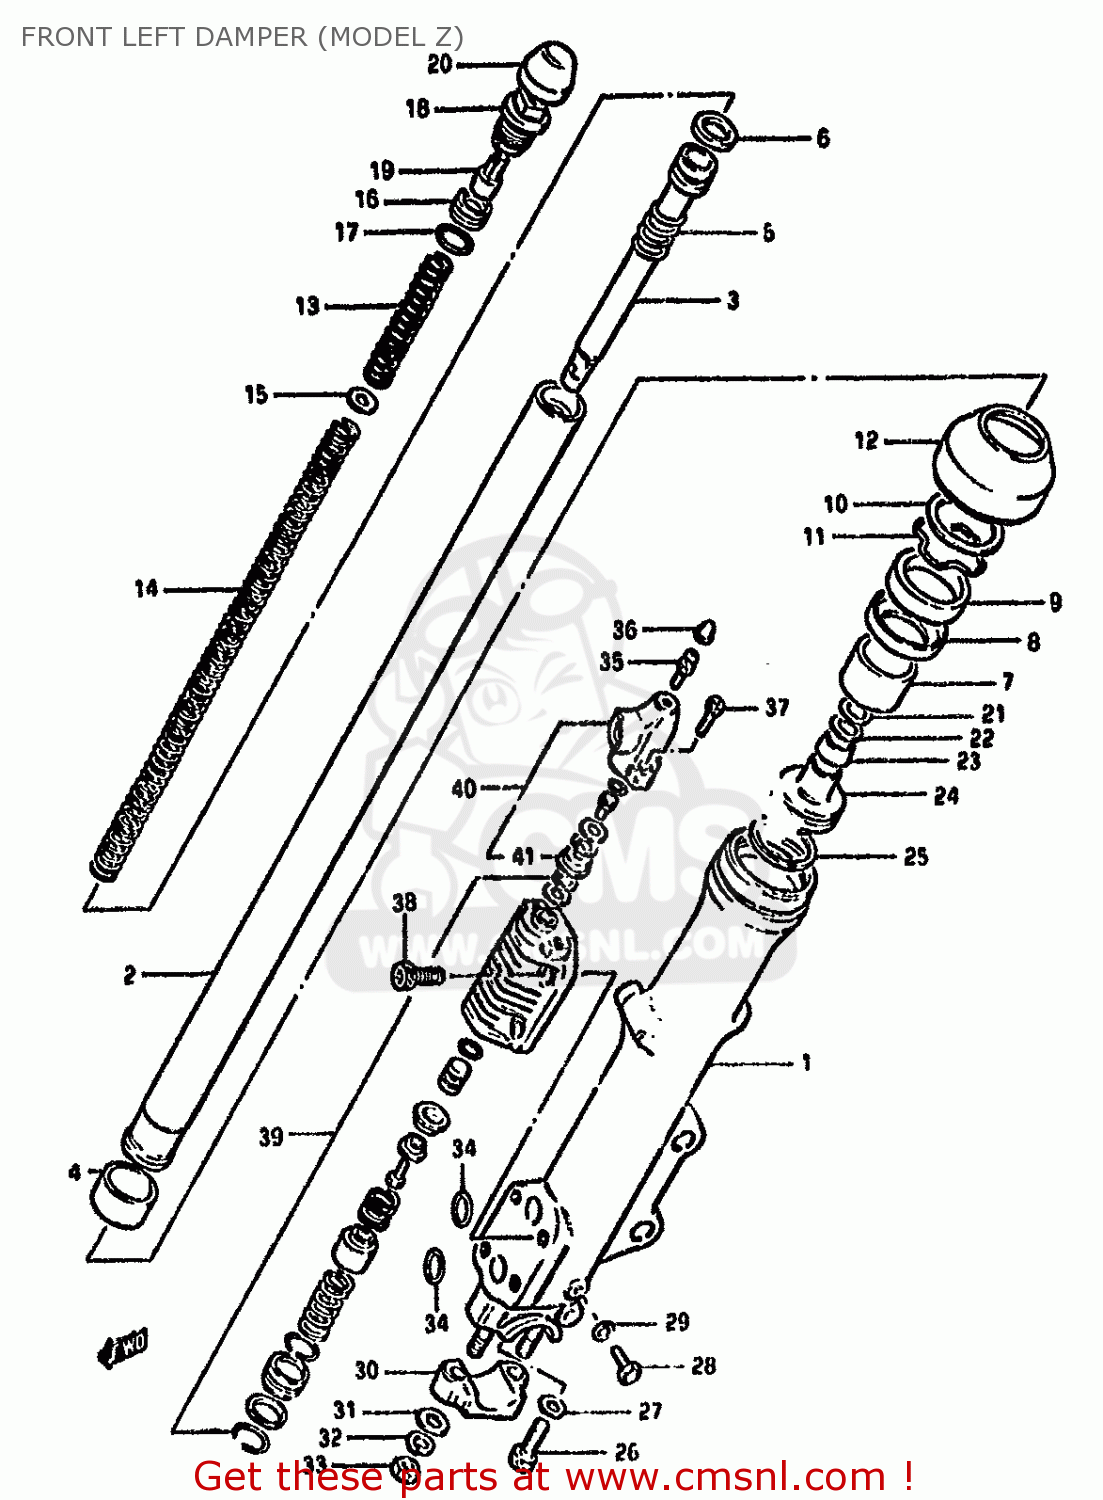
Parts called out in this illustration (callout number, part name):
1	OUTER TUBE LH
2	INNER TUBE
3	CYLINDER
4	PISTON
5	SPRING,FORK REBOUND
6	RING
7	BUSH,GUIDE
8	SPACER,SEAL
9	OIL SEAL,FRONT FORK
10	RING,FR FORK
11	CIRCLIP,FORK OIL SEAL
12	BOOT
13	SPRING (A)
14	SPRING (B)
15	WASHER,SPRING
16	SEAT, SPRING
17	O-RING
18	BOLT
19	ADJUSTER,SPRING
20	CAP
21	VALVE
22	SPRING,VALVE
23	VALVE,OIL LOCK PIEACE
24	PIECE,FRONT FORK OIL LOCK
25	PISTON RING,FRONT FORK
26	BOLT(8X27)
27	GASKET (NAS)
28	BOLT
29	GASKET,DRAIN,PLUG (NAS)
30	HOLDER,AXLE
31	LOCK WASHER
32	LOCK WASHER
33	NUT
34	O RING,FR FORK
35	BREATHER
36	CAP
37	BOLT
38	BOLT
39	MODULATOR VALVE SET,FRONT
40	MODULATOR PARTS SET,FRONT
41	SEPARATOR,FRONT FORK MODULATOR
